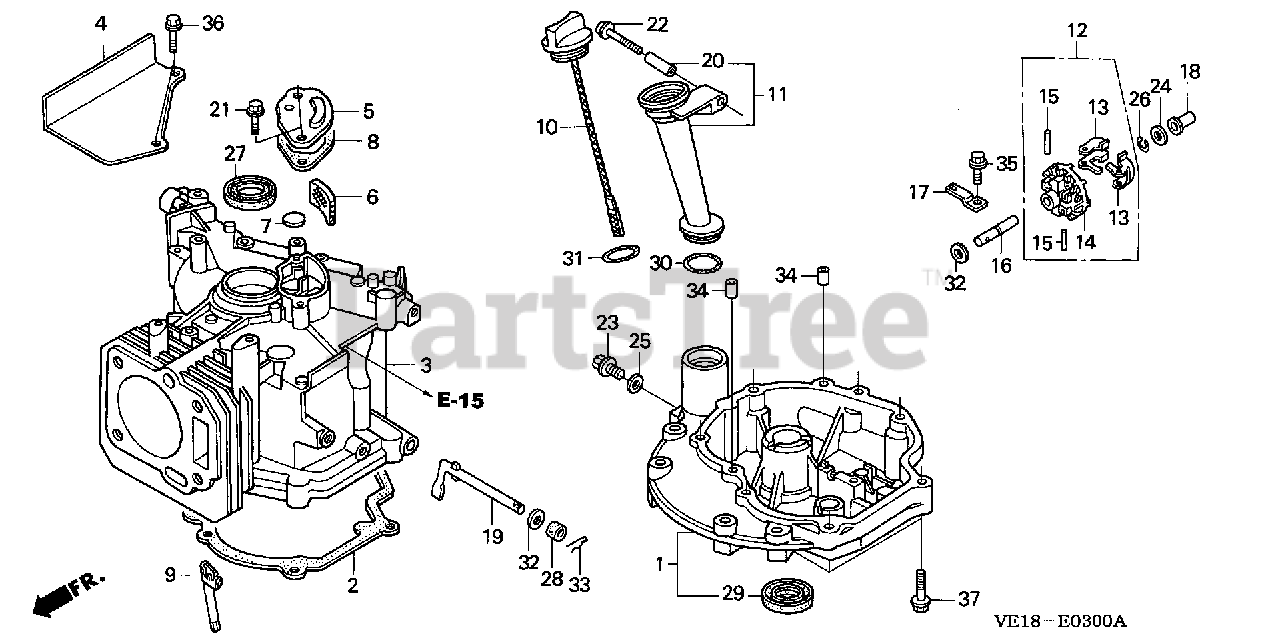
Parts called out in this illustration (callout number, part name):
1	PAN ASSY., OIL
2	GASKET, OIL PAN
3	CYLINDER
4	PLATE, GUIDE
5	CAP, BREATHER CHAMBER
6	FILTER, BREATHER
7	VALVE, BREATHER
8	GASKET, BREATHER CHAMBER
9	PIPE, OIL DEFENSE
10	DIPSTICK, OIL
11	EXTENSION, OIL FILLER
12	GOVERNOR ASSY.
13	WEIGHT, GOVERNOR
14	HOLDER, GOVERNOR WEIGHT
15	PIN, GOVERNOR WEIGHT
16	SHAFT, GOVERNOR HOLDER
17	PLATE, GOVERNOR SHAFT HOLDER
18	SLIDER, GOVERNOR
19	SHAFT, GOVERNOR ARM
20	COLLAR, EXTENSION
21	BOLT, FLANGE (6X14) (CT200)
22	BOLT, FLANGE (6X32) (CT200)
23	BOLT, DRAIN PLUG
24	WASHER, THRUST (6MM)
25	WASHER, DRAIN PLUG (10.2MM)
26	CLIP, GOVERNOR HOLDER
27	OIL SEAL (22X35X6)
28	OIL SEAL (6X11X4) (ARAI)
29	OIL SEAL (25X38X7)
29	OIL SEAL (25X38X7) (ARAI)
30	O-RING (22.1X2.2)
31	O-RING (26X2.7)
32	WASHER, PLAIN (6MM)
33	PIN, LOCK (8MM)
34	PIN, DOWEL (8X14)
35	BOLT, FLANGE (6X12)
36	BOLT, FLANGE (6X20)
37	BOLT, FLANGE (6X28)
